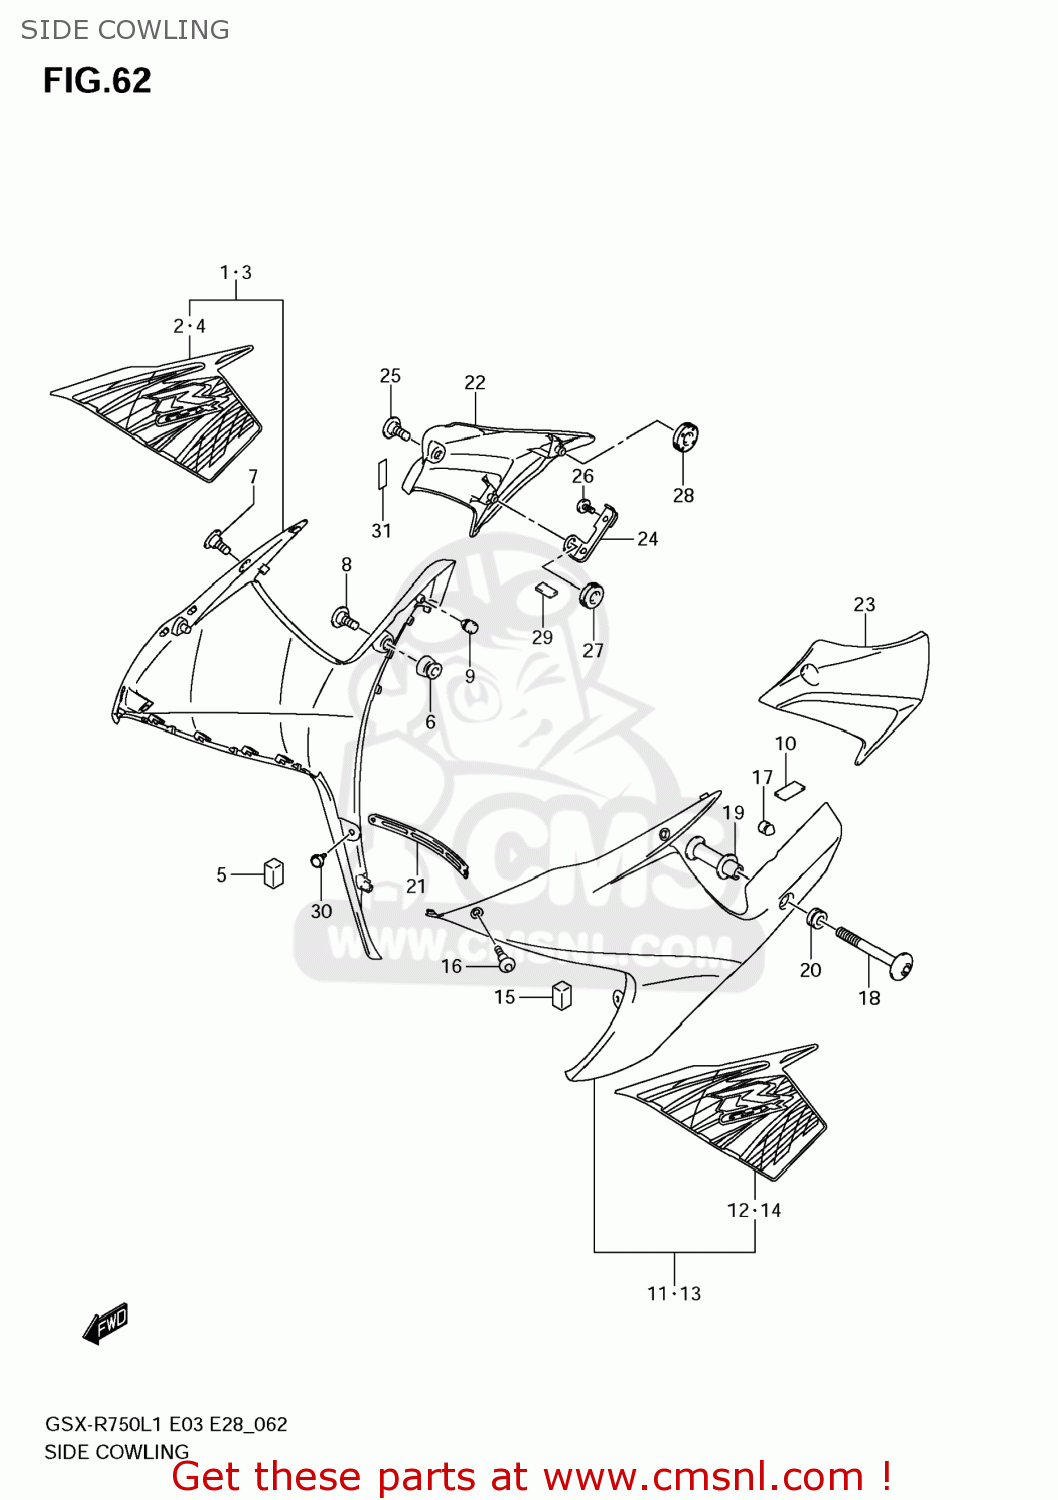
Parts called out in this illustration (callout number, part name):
1	COWLING,SIDE,R(WHITE)
2	EMBLEM,GSXR,R
3	COWLING,SIDE,R(BLACK)
4	TAPE,SIDE COWLING,R
5	CUSHION,SIDE C
6	CUSHION,UNDER COWLING,L
7	SCREW(5X13)
8	BOLT(6X20)
9	CUSHION
10	CUSHION,FUEL TANK NO.2
11	COWLING,SIDE,L(WHITE)
12	EMBLEM,GSXR,L
13	COWLING,SIDE,L(BLACK)
14	TAPE,SIDE COWLING,L
15	CUSHION,SIDE C
16	SCREW(5X13)
17	CUSHION
18	SCREW,SIDE COWL,L
19	SPACER,SIDE COWL,L
20	CUSHION
21	PLATE,UNDER COWL CTR
22	COVER,SIDE COWLING,R
23	COVER,SIDE COWLING,L
24	BRACKET,COVER SIDE,R
25	SCREW(5X13)
26	SCREW(6X12)
27	CUSHION
28	CUSHION
29	CUSHION
30	CLIP
31	TAPE(6X25X0.13)
